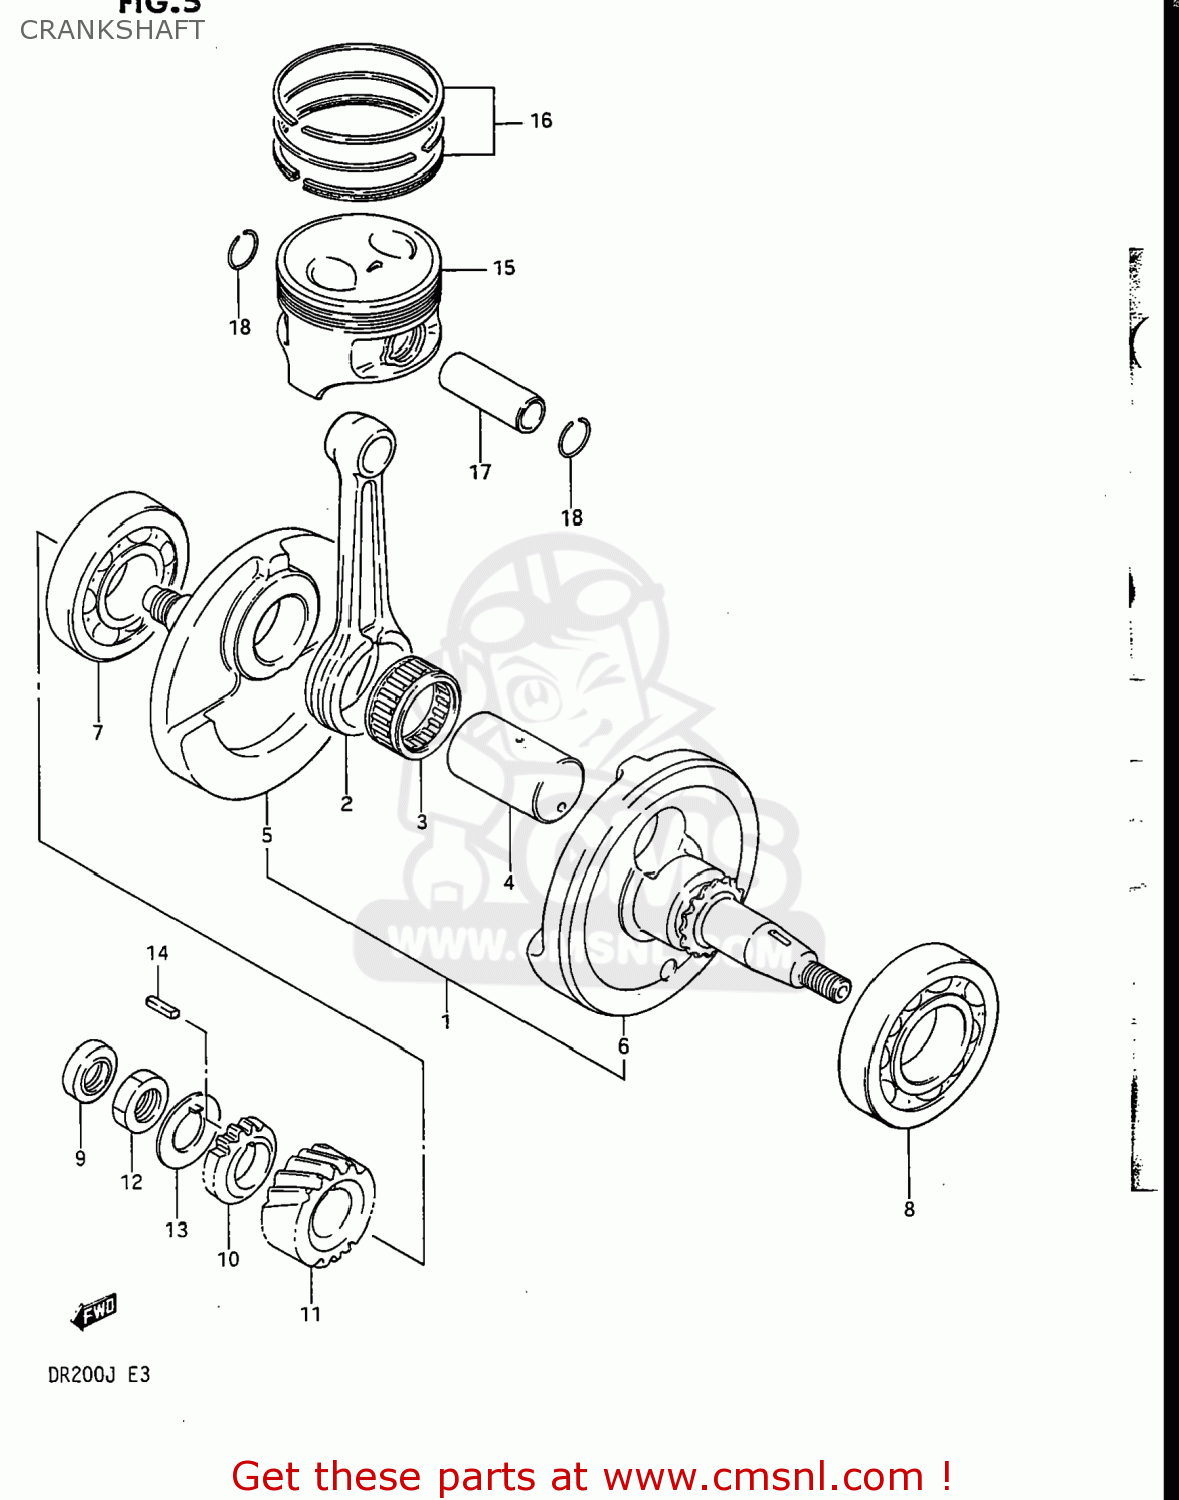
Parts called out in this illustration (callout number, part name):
1	CRANKSHAFT ASSEMBLY
2	CONNECTING ROD
3	BEARING(31X38X18)
4	PIN,CRANK
5	CRANKSHAFT,R
6	CRANKSHAFT,LEFT
7	BEARING(28X68X18)
8	BEARING
9	OIL SEAL
10	GEAR,OIL PUMP DRIVE(NT:15)
11	GEAR,PRIMARY DRIVE (NT:
12	NUT
13	WASHER
14	KEY
15	PISTON
16	RING SET,PISTON
17	PIN,PISTON
18	CIRCLIP
